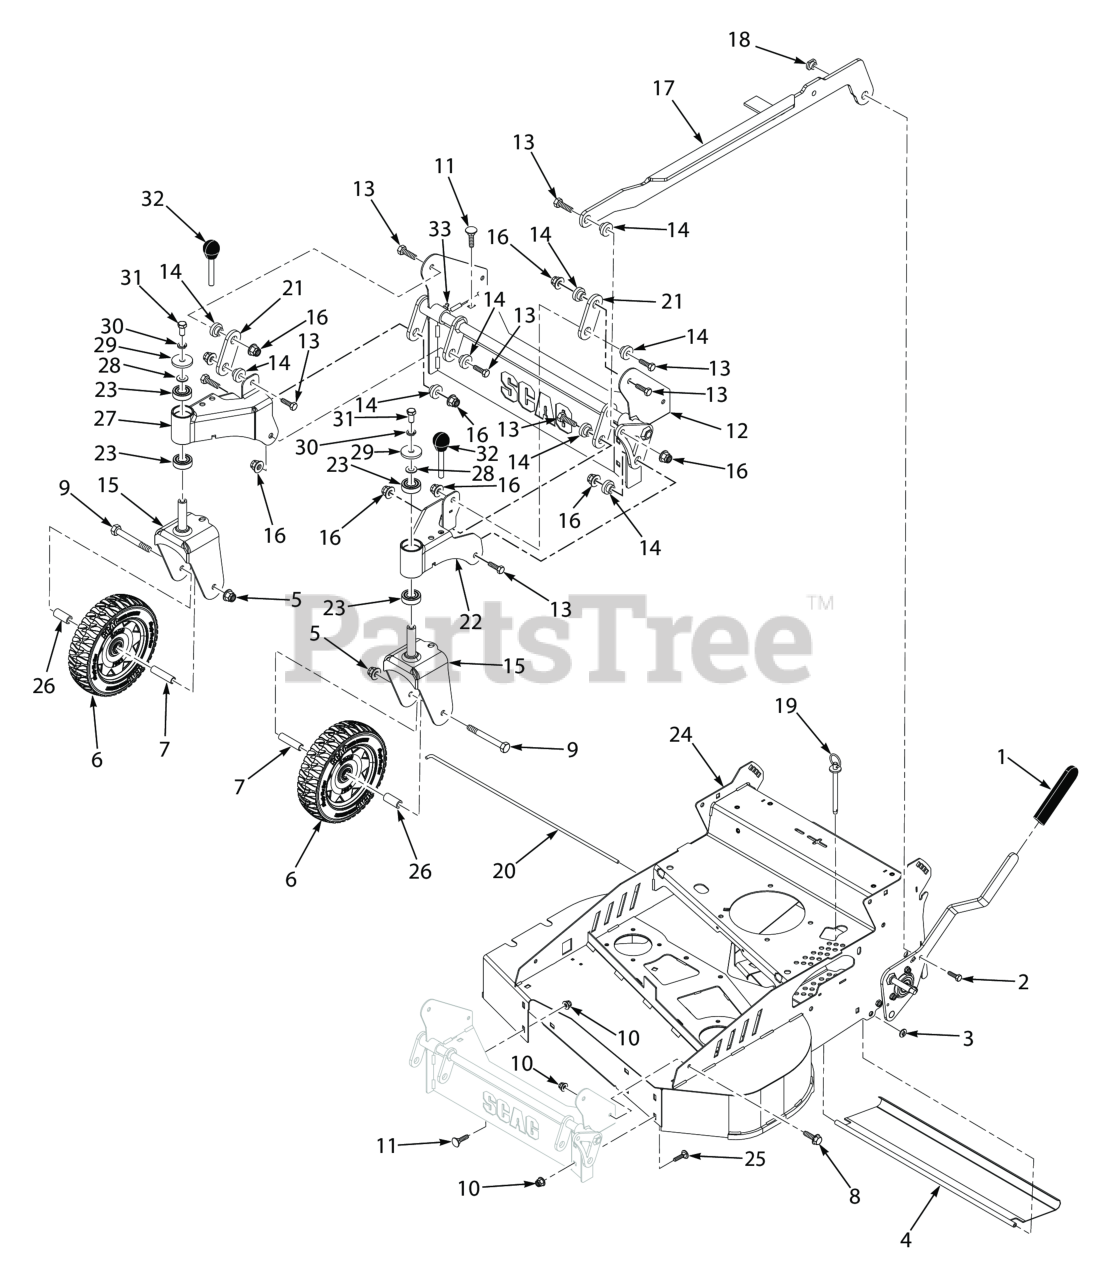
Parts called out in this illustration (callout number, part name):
1	Grip, Deck Lift
2	Bolt, Hex Head, 3/8-16 x 3/4"
3	Nut, Push-On 5/16-18
4	Trail Shield
5	Nut, Flange Elastic Stop Nut, 3/8-16
6	Wheel Assembly, Front
7	Spacer, Front Wheel
8	Cpscrw, 5/16-18 x 1"Serrated Flange Hex Head
9	Bolt, Hex Head 3/8-16 x 4.00
10	Nut, Flange Head Elastic Stop 5/16-18
11	Bolt, 5/16-18 x .75 RHSN Carriage
12	Caster Lift Support Weldment
13	Bolt, Hex Head 3/8-16 x 1-1/4", Kawasaki FX / FT & FT-EFI
14	BUSHING, SPEED ADJUSTMENT LEVER
15	Yoke Weldment
16	Nut, Flange Elastic Stop Nut, 3/8-16
17	Weldment Deck Lift
18	Pivot, Deck Weldment
19	Ring Pin, 3/8 x 4"
20	Rod, Trail Shield
21	Bracket, Link
22	Yoke Support Weldment, LH
23	BEARINGS, BALL, NEUTRAL RETURN
24	Cutter Deck w/ Decals
25	Bolt, Carriage 5/16-18x1" (large frame units only)
26	Pivot, Brake Lever
27	Yoke Support Weldment, RH
28	Flatwasher, 3/8 (.406 x .812 x .065)
29	Flatwasher, 3/8-.406 x 1-1-1/2 x 7 Gauge
30	Lockwasher, 3/8" Spring, Kawasaki FX / FT & FT-EFI / B&S 32BV
31	Bolt, Hex Head, 3/8-16 x 3/4"
32	Pin Assembly, Swivel Lock
33	GREASE FITTING, STR. 1/4-28 SELF TAP.
